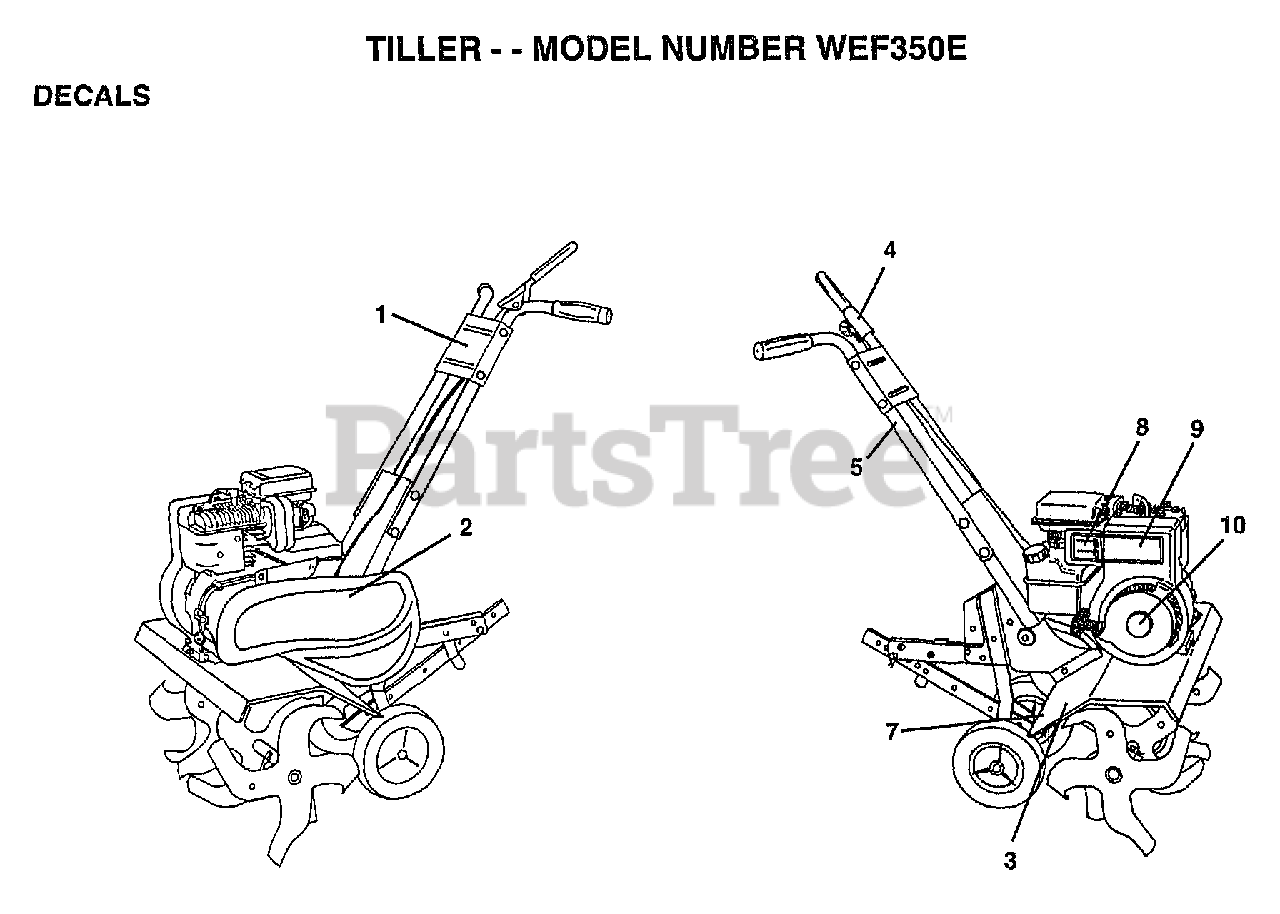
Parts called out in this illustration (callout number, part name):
1	DECAL.LOGO.CONTROL
3	DECAL.CAUTION
4	DECAL TI
5	DECAL TI
8	DECAL.SPEED.CONTROL
